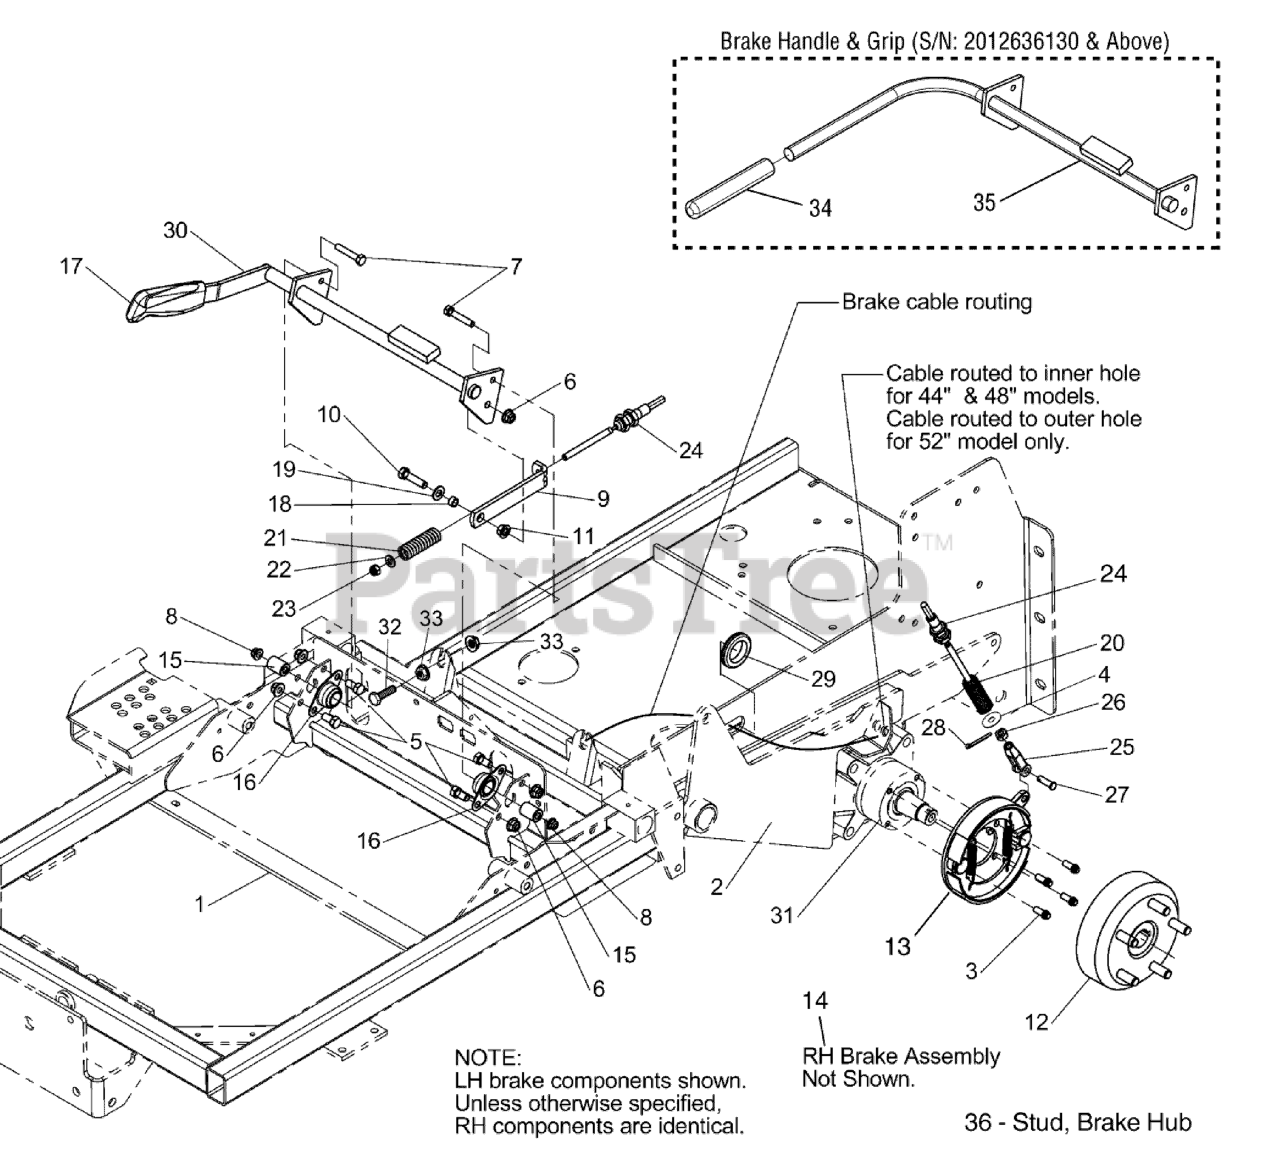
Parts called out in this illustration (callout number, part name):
1	MAIN FRAME
2	MOTOR MOUNT
3	BOLT, 5/16-18 X 3/4 12PT FLANGE - PATCH
4	WASHER, 5/16" USS
5	BOLT, 3/8-16 X 3/4" GD5 CZ
6	NUT, 3/8-16 Hex Nylock Flange
7	BOLT, 5/16-18 X 1-3/4"
8	NUT, 5/16-18 Hex Nylock Flange
9	LINK, BRAKE STOP, 6.0 - BLK
10	BOLT, 3/8-16 X 1-1/2" GD5 CZ
11	NUT, 3/8-16 Hex Serrated Flange
12	BRAKE DRUM, 6", 5 BOLT, KNOTT
15	SPACER, .32 X .75 X 1.06
16	BEARING, Flange
17	GRIP, BLACK FLEXIBLE
18	SPACER, .38 X .50 X .27
19	WASHER, 3/8 SAE
20	SPRING, Compression
21	SPRING, Compression
22	WASHER, 5/16" SAE
23	NUT, 5/16-24 HEX NYLON LOCK
25	CLEVIS, 5/16-24, STEEL, CLEAR ZINC
26	NUT, 5/16-24 Hex
27	CLEVIS PIN, 5/16" X 1"
28	PIN, HAIR, .0585" X 1-1/8"
29	GROMMET, 1-1/4"
30	BRAKE SHAFT
31	WHEEL MOTOR
32	BOLT, 5/16"-18 X 1 1/8"
33	NUT, 5/16-18 HEX SERRATED FLANGE (LARGE)
34	GRIP, FOAM, 3/4 ID X 6 X .187
35	WELD, BRAKE SHAFT - BLK
36	STUD, BRAKE HUB (SV)
